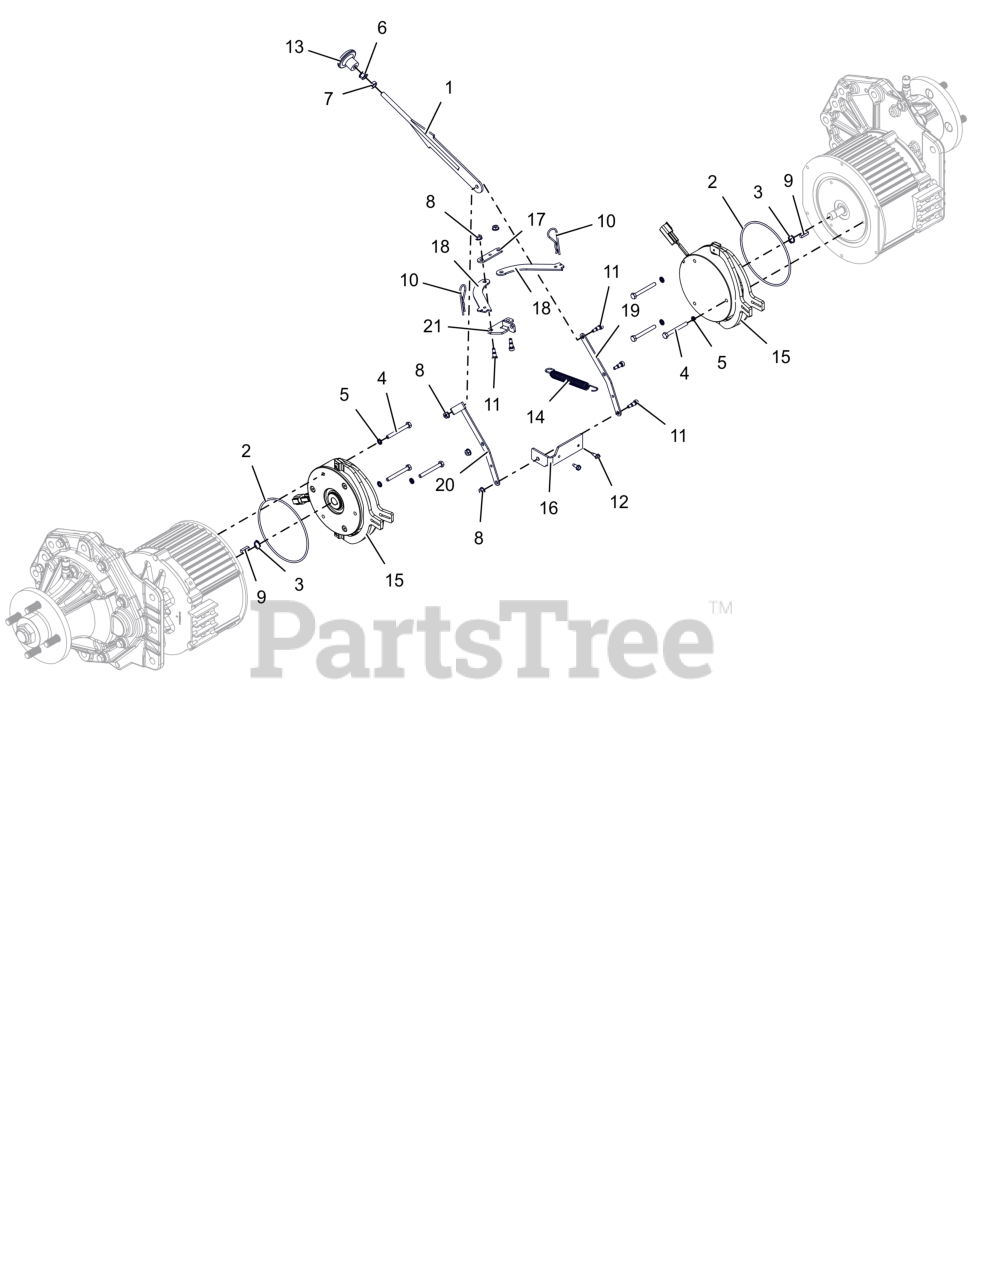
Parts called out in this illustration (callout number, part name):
1	WLDMT, BRAKE ARM
2	O-RING 126MM IDX3MM
3	RING, RETAINING-EXTERNAL 25MM X 1.2MM
4	BLT,HEX M6-1X55 EP30 G8.8 ZCC
5	WSHR-FL-STL, SEAL 6MMX11MMX1MM
6	NUT,LK-CTR-FLG .31-18 GF ZCC
7	NUT-JAM .312-18 G2 ZCC
8	NUT, FLG-TOP LK #10-24 GF ZCC
9	KEY-STR 5X5X18MM RD ENDS
10	PIN, HAIR-#7 .094X2.31 ZC120
11	BLT-SHLDR .25X.375
12	SCR,TAP #10-24X.50 HWH TR ZCC
13	KNOB, PUSH -PULL .312-18
14	SPRING, SWIVEL HOOK EXTENSION
15	BRAKE, MOTOR
16	PIVOT, BRAKE LINK MAIN
17	PLATE, BRAKE PULL DOUBLER
18	LINK, PUSH
19	LINK MIDDLE
20	LINK- MIDDLE
21	LINK- T
